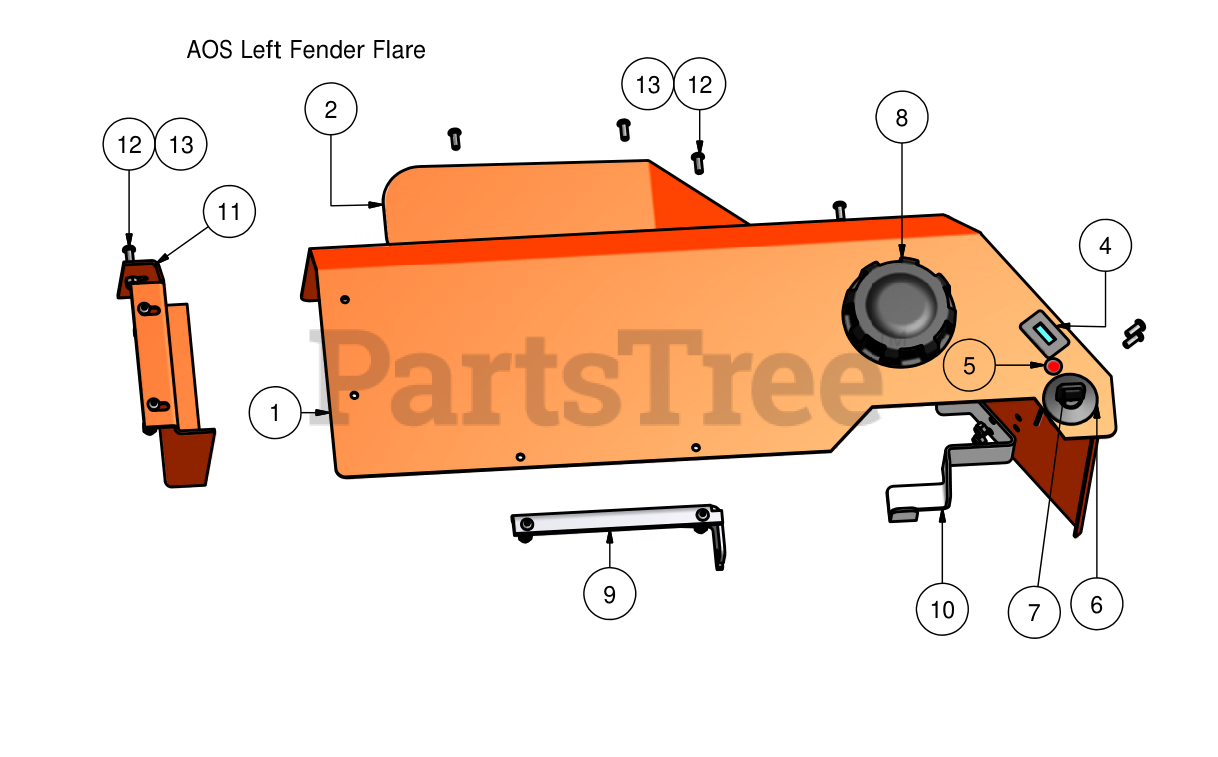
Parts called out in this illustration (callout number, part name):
1	Left fender (5 gallon 2004)
2	Fender flare (left)
3	5 Gallon Fuel Tank
4	Tachometer
6	Ignition Switch
7	Ignition Key
9	Left tank retainer (5 gallon)
10	Front tank retainer (left 5 gallon)
11	Left End Tank Braket
12	1/4" x 5/8" Buttonhead Bolt
13	1/4" Nylock Nut
